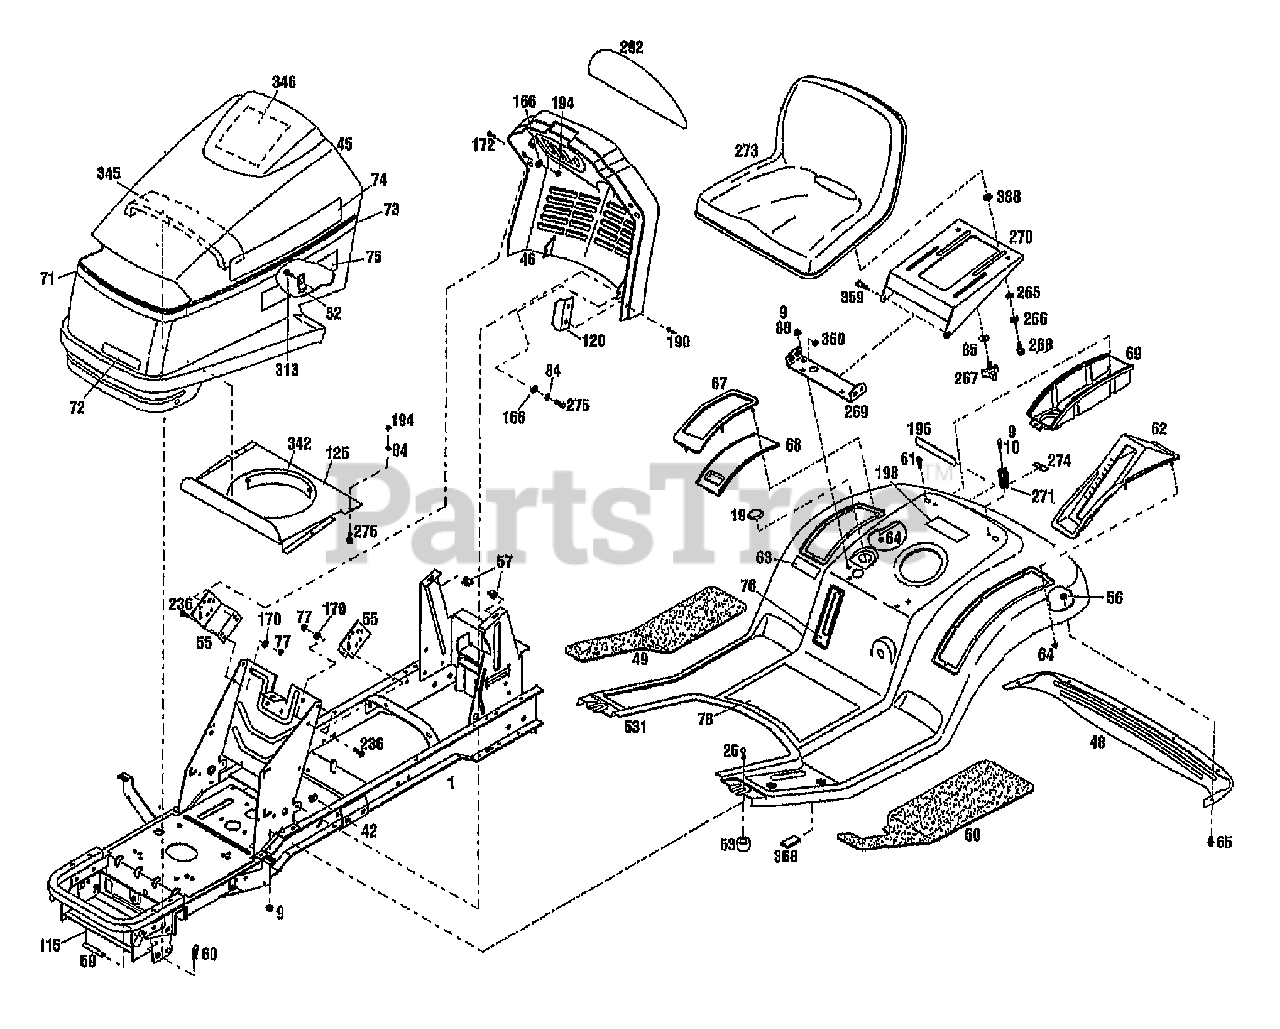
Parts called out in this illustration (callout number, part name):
1	ASSM-FRAME LTX
9	NUT-HFLK 5/16-18 ZP
10	SCR-HHC 5/16-18X.75 GR 5 ZP
19	PLUG 2.50
26	SCR-CARR 5/16-18X1.0 G2 ZP
42	NUT-SPEED
45	HOOD-TRACTOR
46	CONSOLE
48	TRIM-FENDER REAR
49	PAD-FOOT RH
50	PAD-FOOT LH
52	LATCH
53	SPACER-TUBULAR
55	BRKT-MOUNTING
56	NUT-HF/LK 1/4-20 ZP
57	NUT-SELF RETAIN 5/16-18
59	PIN-PIVOT HOOD
60	PIN-HITCH .125X2.56 ZP
61	SCR-LOCK
62	COVER-LIFT HANDLE
63	DECAL-AMERICAN LEGEND-LRG
64	NUT-SELF THREADING
65	SCR-HH 1/4-20X.625
67	TOP-STORAGE COVER
68	COVER-CONTAINER
69	CONTAINER-STORAGE
71	DECAL-STRIPE HOOD FRONT
72	DECAL-LOGO
73	DECAL-STRIPE SIDE
74	DECAL-LOGO TROY-BILT
75	DECAL-MODEL 13035 {13085}
75	DECAL-MODEL 13036 {13086}
76	DECAL-FUEL LEVEL
77	NUT-HEX 5/16-18 ZP
78	DECAL-OPER INST
84	WASHER-LK .25 ZP
85	WASHER-FLAT 3/8 SAE
88	SCR-CARR 5/16-18X.62 G2 ZP
115	PIN-ROLL .188X1.0
120	BRKT-HOOD ALIGN
125	SHIELD-HEAT UPPER
166	WASHER-FLAT 1.25X.28X.062 ZP
170	WASHER-LK .312 ZP
190	RIVET-POP
194	NUT-HEX 1/4-20 ZP
196	DECAL-LOGO FENDER
198	DECAL-FUEL
236	SCR-HFLK 5/16-18X.75 ZP
265	WASHER-1.06X.51X.09 NYLON
266	WASHER-BOW .74X.52X.01
268	SCR-SHLDR 3/8-16X.25 G5ZP
269	BRKT-SUPPORT SEAT
270	SUPPORT-SEAT
271	SPRING-COMPRESSION
273	KIT-SEAT (TRACTOR) {13085}
273	KIT-SEAT (TRACTOR) {1766461}(13086)
274	BRKT-SPRING HOLD DOWN
275	SCR-HH 1/4-20X.625 G5 ZP
292	LENS-INSTRMTS WARN LIGHTS(13085,13086)
342	GASKET-HEAT SHIELD
345	STRIP-SEALING
346	DECAL-SERVICE
359	SCR-HH 3/8-16X.88 G5 ZP
360	NUT-H/LK 3/8-16
388	WASHER-FLAT
531	FENDER-GREEN W/DECALS
